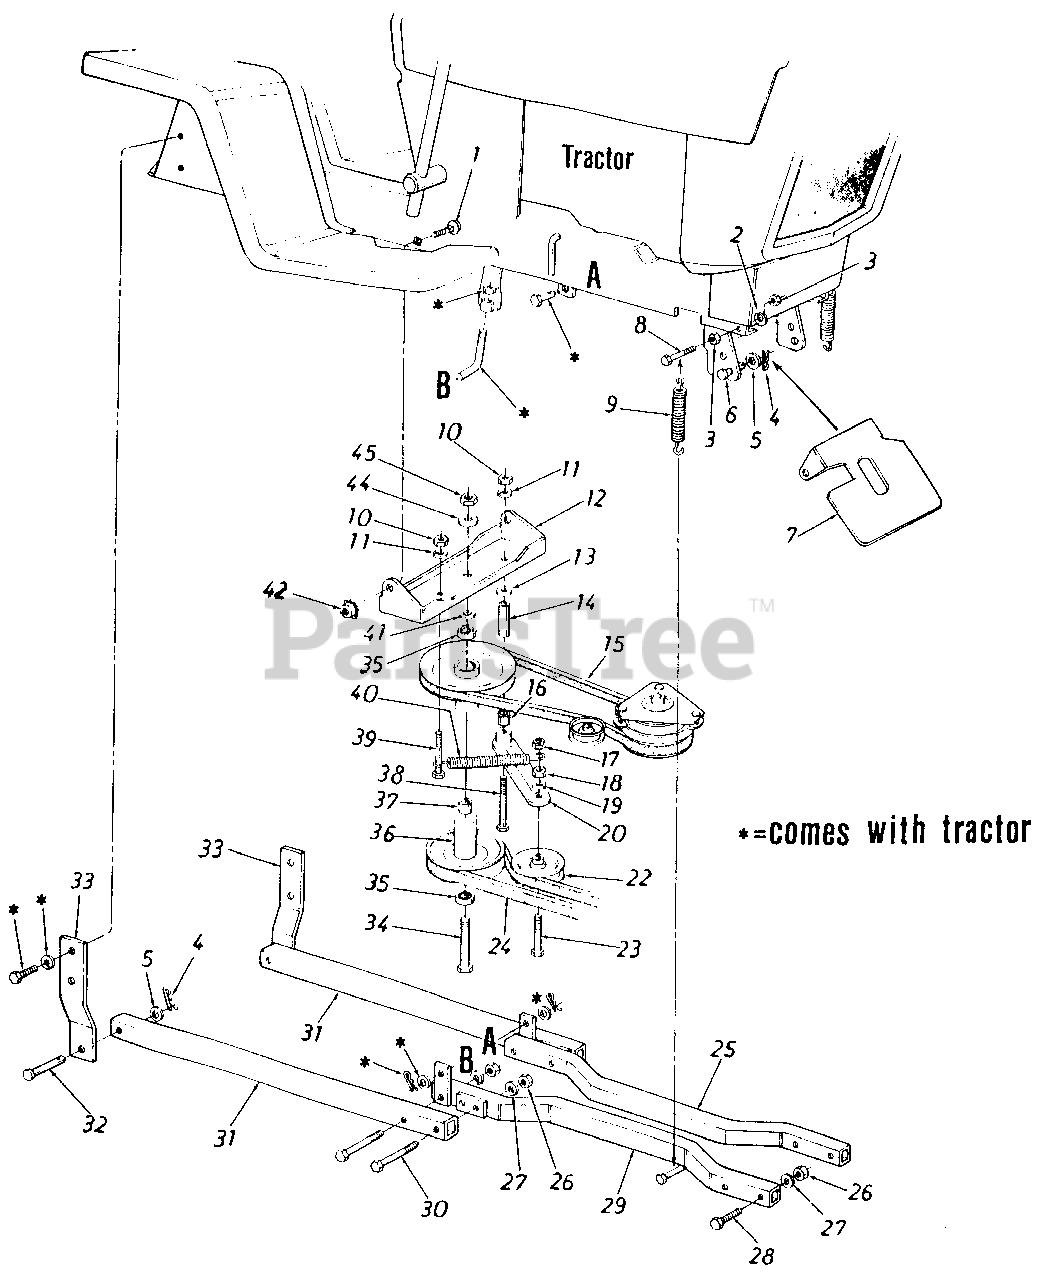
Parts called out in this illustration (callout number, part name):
1	BOLT, 5/16-18 X .62 CRG
2	WASHER, 1/4 LOCK
3	NUT, 1/4-28
4	PIN, 1/2 INT COT
5	WASHER, .510 X 1.0 FLAT
6	PIN, LIFT BRACKET
7	BRACKET, GUIDE (.510 DIA)
8	BOLT, 1/4-28 X 1.25
9	SPRING, EXTENSION .81 OD X 4.75 LONG
10	NUT, 3/8-16 JAM
11	WASHER, 3/8 BLELLEVILLE
12	BRACKET, JACKSHAFT SUPPORT
13	WASHER, 3/8 BLELLEVILLE
14	SPACER, .37 X .562 X 1.50 LONG
15	BELT, V (1/2 X 47" LONG) (A POLYSTER)
16	SPACER, .377 X .600 X .830 LONG
17	NUT, 3/8-16 LOCK
18	NUT, 3/8-16 JAM
19	WASHER, 3/8 LOCK
20	ARM ASSY. IDLER
22	PULLEY, IDLER
23	BOLT, 3/8-16 X 2.25
24	BELT, V (1/2 X 88.0" LONG) (A POLYSTER)
27	WASHER, 1/2 LOCK
28	BOLT, 1/2-13 X 2.75
29	TUBE ASSY. FRONT SUPPORT RH
30	BOLT, 1/2-13 X 4
31	TUBE, 1-1/2 X 38.0 IN. LONG SQ
32	PIN, .50 X 2.19 CLEVIS
33	PLATE, REAR HANGER
34	BOLT, 5/16-18 X 4.50
35	BEARING, BALL (.62 ID X 1.38 OF X .44)
36	PULLEY, DOUBLE GROOVE
37	SPACER, PULLEY
38	BOLT, 3.8-16 X 3.25
39	BOLT, 3/8-16 X 2.25
40	SPRING, EXTENSION (.54 OD X 5.25" LONG)
41	WASHER, 5/8 X 1 X .063
42	NUT, 5/16-18
44	WASHER, .630 X 1.25 BELLEVILLE
45	NUT, 5/16-18 JAM
